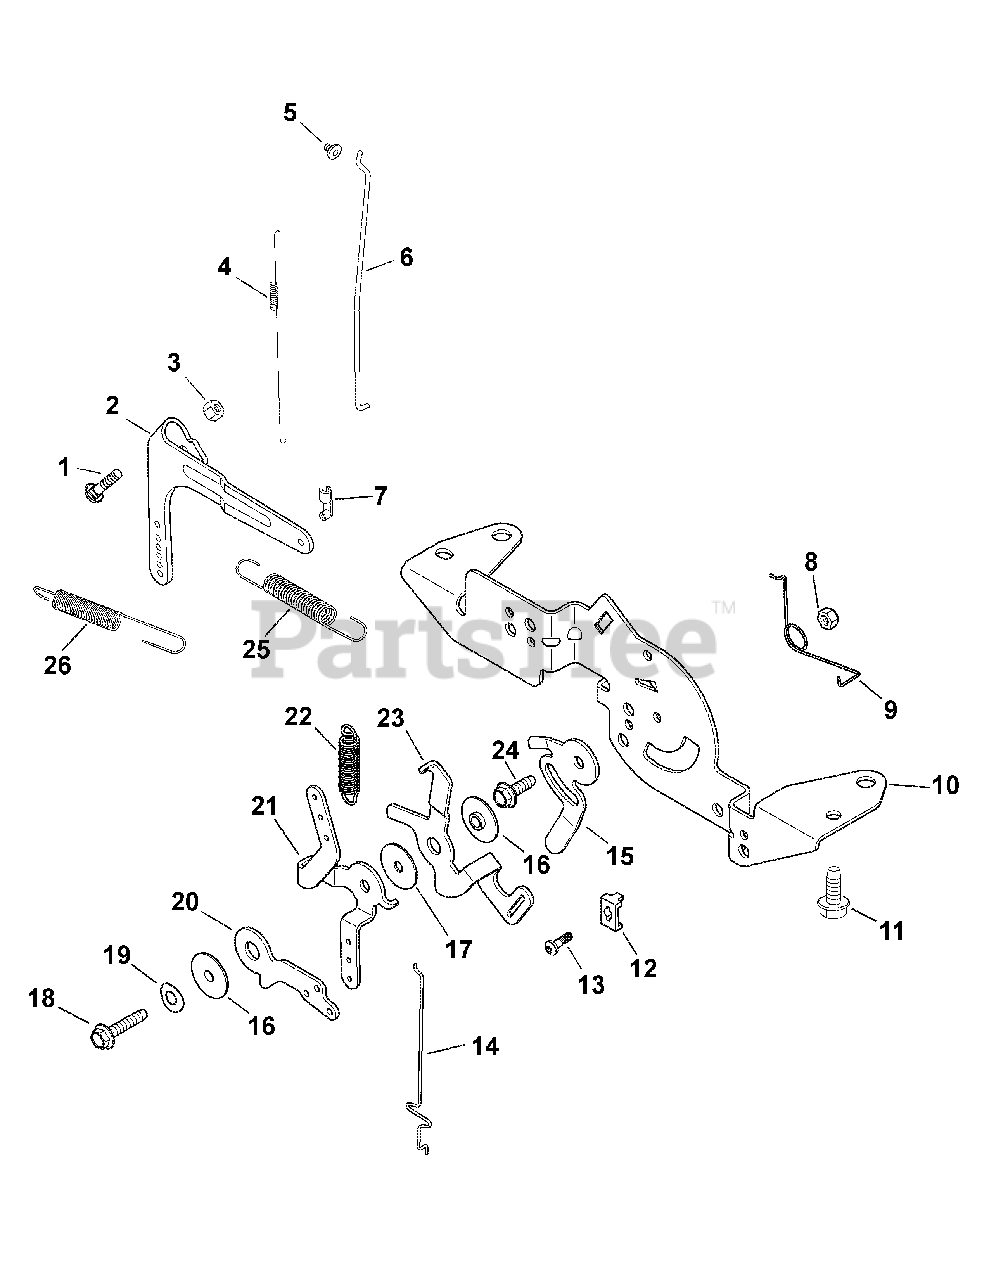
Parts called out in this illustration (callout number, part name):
1	Bolt, Carriage, M6 X 1.0 X 25
2	Lever, Governor
3	Nut, Flange, M6 x 1.0
4	Spring, Linkage
5	Bushing, Linkage Retainer
6	Linkage, Throttle
7	Bushing, Throttle Linkage
8	Nut, Lock, M5 x 0.8
9	Spring, Choke Return
10	Bracket, Control
11	Screw, Flnge Thrd. Frmng M6 x 1.0 x 16
12	Clamp, Cable
13	Screw, Torx Hd. Ctsk, M5 x 0.8 x 16
14	Linkage, Choke
15	Lever, Speed Setting
16	Spacer, Control Assembly
17	Washer, Flat, 5.5mm
18	Screw, Thrd. Forming, M5 x 0.8 x 25
19	Washer, Spring, 1/4
21	Lever, Speed Control
22	Spring, Speed Control
23	Lever, Governor Spring
24	Screw, Flng. Thrd. Frmng, M5 x 0.8 x 16
25	Spring, Governor
26	Spring, Governor
